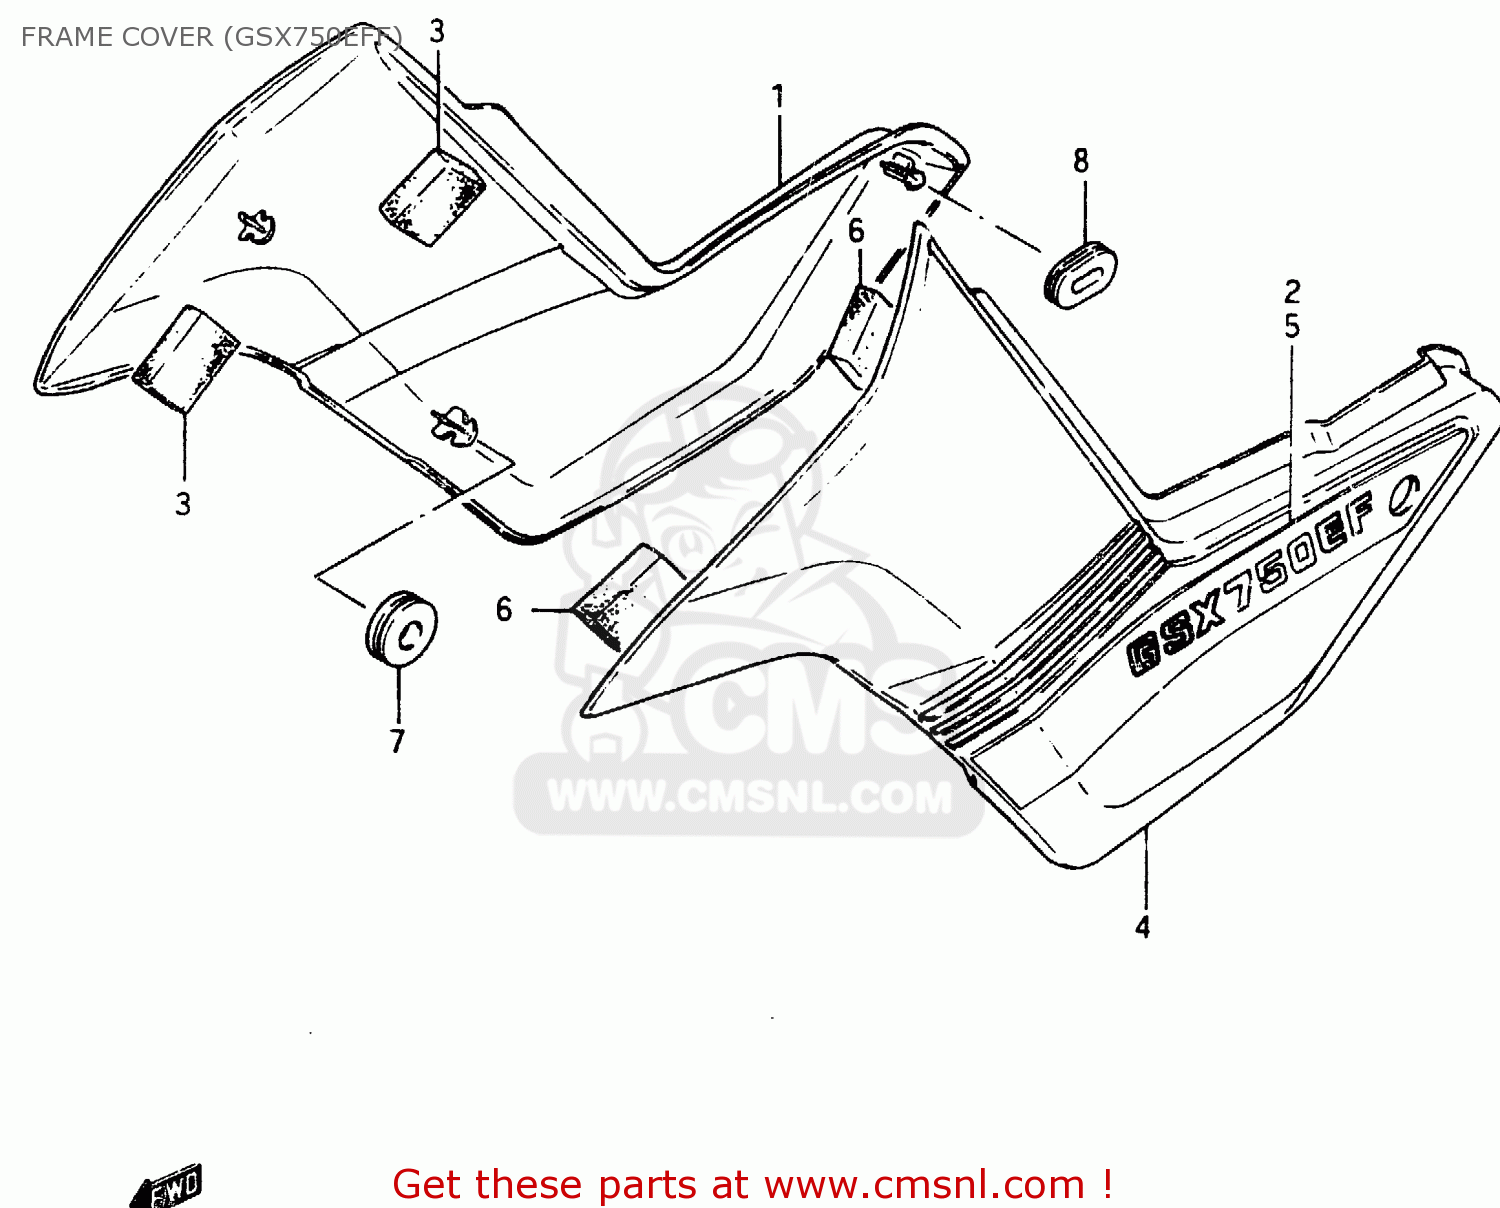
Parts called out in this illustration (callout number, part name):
1	COVER, FRAME RH
2	TAPE SET, FRAME COVER RH
3	CUSHION
4	COVER, FRAME LH
5	TAPE SET, FRAME COVER LH
6	CUSHION
7	CUSHION
8	CUSHION
